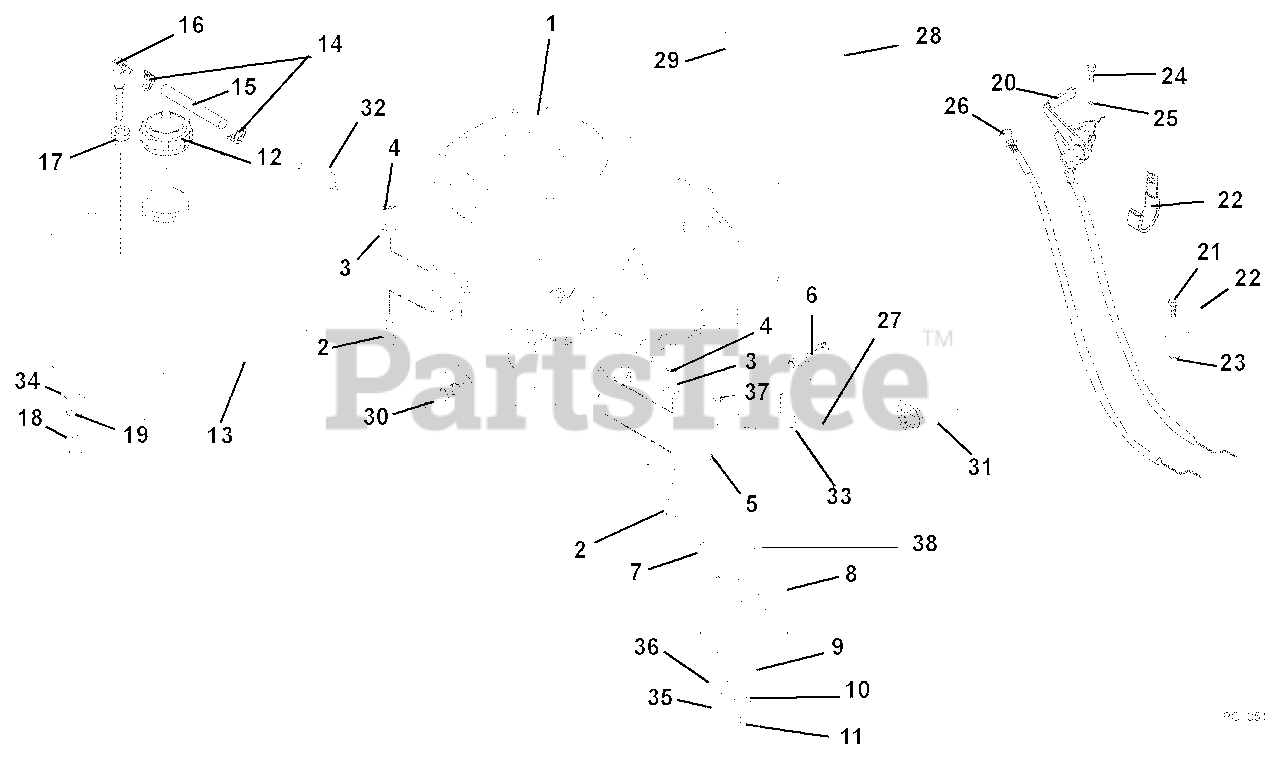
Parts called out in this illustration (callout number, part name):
1	Engine, 15 HP Kawasaki FH430V - AS02 (105, 120)
2	Bolt, Hex .31-18 x 1.75 Grade 5
3	Washer, Locking .31 x .078 Regular
4	Nut, Hex .31-18
5	Bracket, Clutch
6	Valve, Oil Drain
7	Key, Square .25 x 1.25 x 25 SAE 8630 or SAE 1035
8	Clutch, Electric PTO (105, 120, 126, 127 SN 000101 and up) (108, 123, 124, 125 SN 000101
9	Washer, Flat-Steel .469 x 2.00 x .25
10	Washer, Locking .44 x .109 Regular
11	Bolt, Hex .44-20 x 3.00 Grade 5 (105, 120, 126, 127 SN 000101 and up) (108, 123, 124, 125
12	Cap, Fuel
13	Tank, Fuel
14	Clamp, Hose Wire .49/.51 x .116
15	Gas Line, Bulk .25 I.D.
16	Fitting, Tank
17	Bushing (Black in color. Does not replace or interchange with orange colored grommet.)
18	Bolt, Hex .38-16 x .75 Grade 5
19	Washer, Locking .38 x .094 Regular
20	Cable, Throttle with Liner (105, 108, 123, 126)
21	Bolt, Hex .31-18 x .75 Grade 5
23	Nut, Locking-Nylon .312-18
24	Screw, Machine 10-24 x .75 Hex Washer Head
25	Nut, Locking-Nylon 10-24 with Insert
26	Control, Choke
27	Tube, Oil Drain
28	Filter, Air Paper (105, 120)
29	Filter, Air Foam (105, 120)
30	Spark Plug
31	Filter, Oil
32	Fuel Filter, Kawasaki
33	Cable Tie
34	Washer, Flat Steel .409 x .812 x .065
35	Bolt, Hex .312-18 x 2.00 FTH Grade 5
36	Washer, Flat-Steel .344 x .688 x .065
37	Nut, Jam .31-18
38	Bushing, Spacer 1.0 x 1.25 x .25 (105, 120, 126, 127 SN 000101 and up) (108, 123, 124, 125
